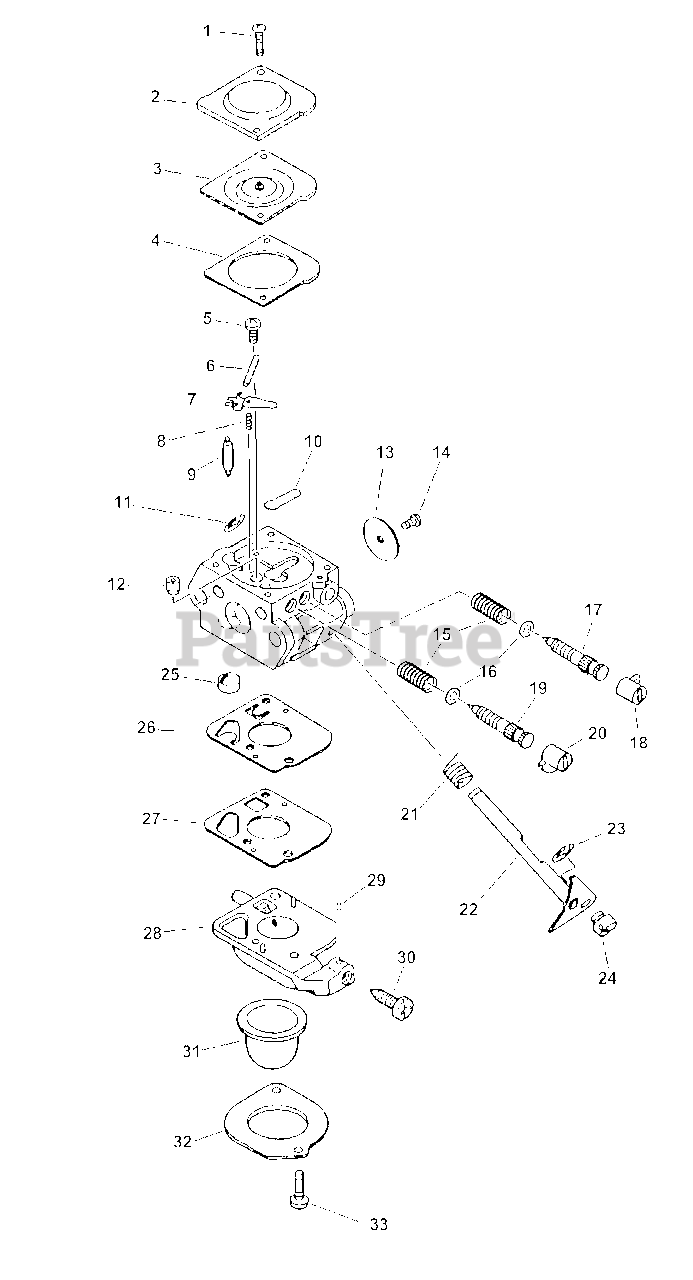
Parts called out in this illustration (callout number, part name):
1	SCREW
2	COVER, METERING DIAPHRAGM
3	DIAPHRAGM, METERING
4	GASKET, METERING
5	SCREW
6	PIN, METERING LEVER
7	LEVER, METERING
8	SPRING, METERING LEVER
9	VALVE, INLET NEEDLE
10	PLUG, WELCH
11	E-RING
12	NOZZLE, CHECK VALVE
13	VALVE, THROTTLE
14	SCREW
15	SPRING, NEEDLE
16	WASHER
17	NEEDLE, IDLE
18	CAP, LIMITER - WHITE
19	NEEDLE, HIGH SPEED
20	CAP, LIMITER - RED
21	SPRING, THROTTLE RETURN
22	SHAFT, THROTTLE
23	CLIP
24	SWIVEL
25	STRAINER
26	DIAPHRAGM, PUMP
27	GASKET, PUMP
28	BODY ASSY, PURGE
29	PIECE, FRICTION
30	SCREW, IDLE ADJUST
31	BULB, PURGE
32	RETAINER
33	SCREW
